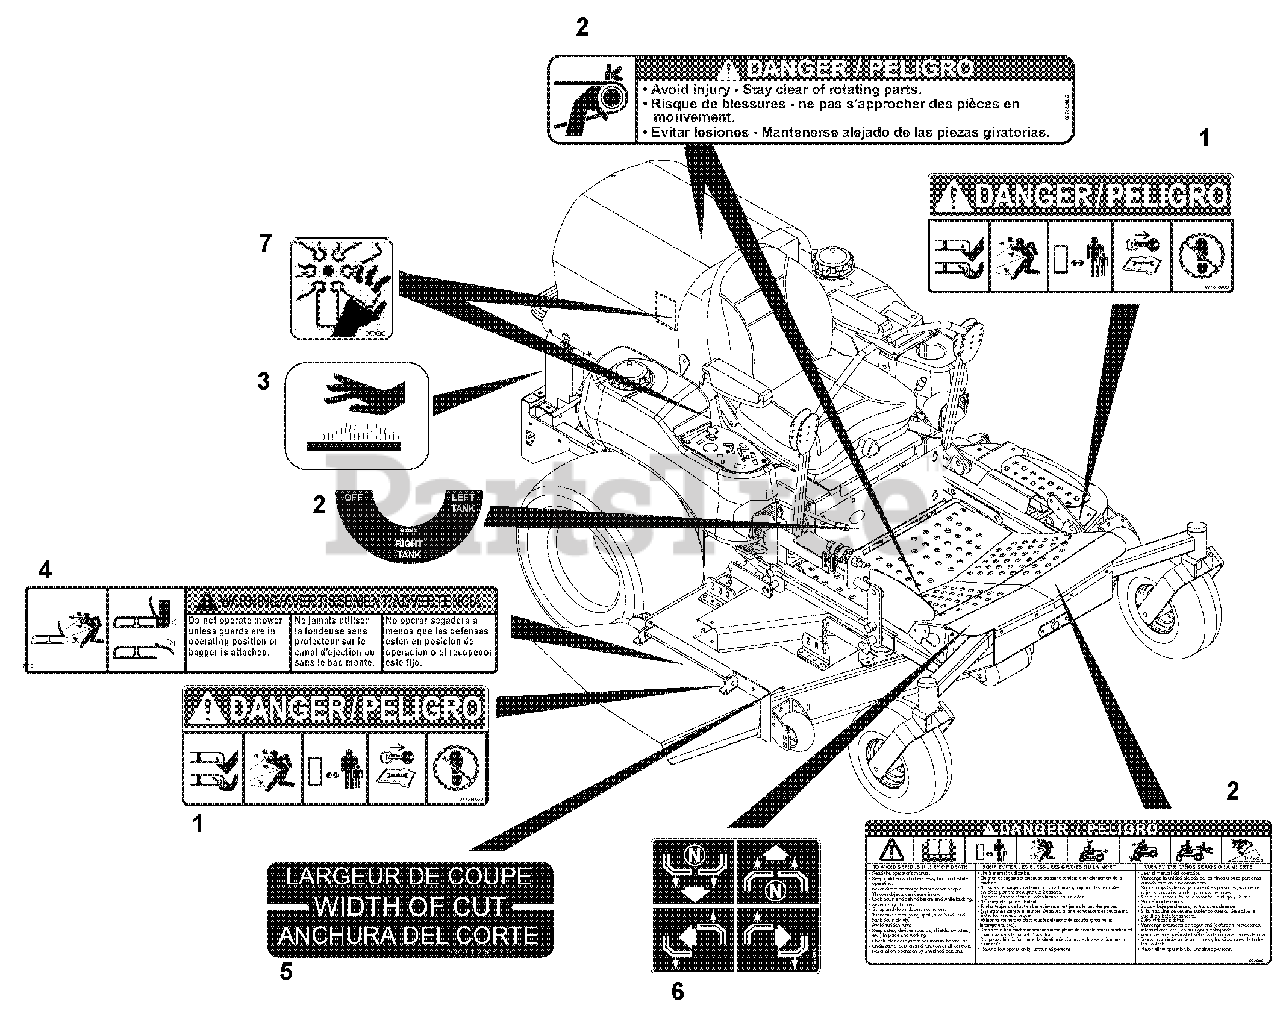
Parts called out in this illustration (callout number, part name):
1	Decal, Mower Pan Head Danger
2	Set, Decal-Common Danger/Fuel
3	Decal-Hot Surface
4	Decal, Warning
5	Decal, Width of Cut
6	Decal-Instructional
7	Decal, Danger Fan
